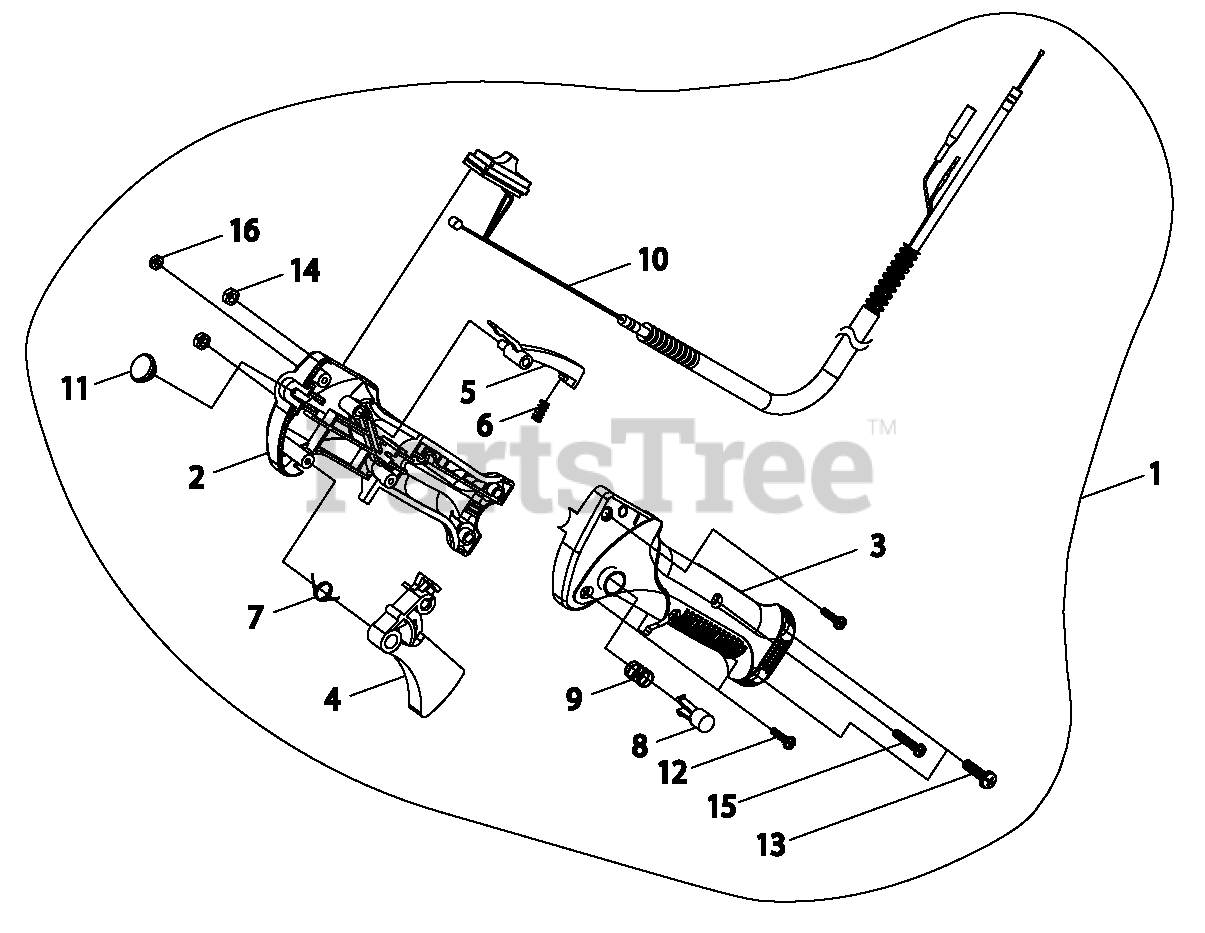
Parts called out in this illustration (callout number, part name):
1	CONTROL HANDLE ASSY
2	HANDLE, CONTROL - RIGHT
3	HANDLE, CONTROL - LEFT
4	TRIGGER, THROTTLE
5	LEVER, TRIGGER LOCKOUT
6	SPRING
7	SPRING, TRIGGER
8	LOCK, THROTTLE
9	SPRING
10	CONTROL CABLE ASSY
11	PLUG
12	SCREW - 4X16 -- TAPPING
13	SCREW - 5X20
14	NUT - 5
15	SCREW - 4X23
16	NUT - 4
